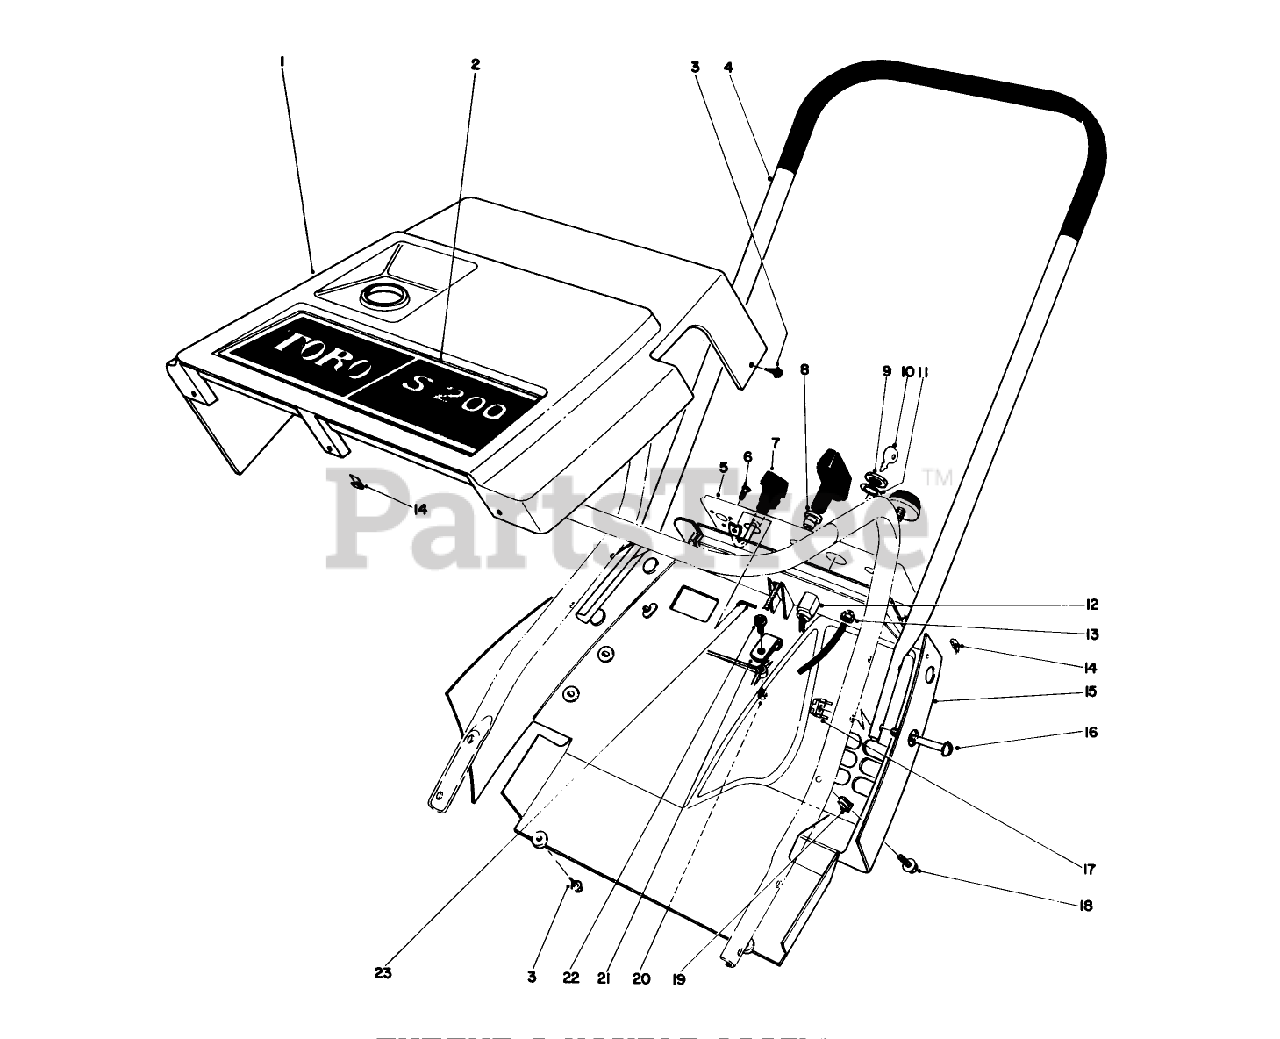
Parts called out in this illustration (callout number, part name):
3	SCREW-HWHTF
6	SCREW-PLASTITE
7	CHOKE CONTROL ASM
8	GUIDE-ROPE, STARTER
9	NUT-HH
11	WASHER-LOCK
13	NUT-KEPS
14	NUT-TYPE J
17	TINNERMAN NUT
18	SCREW-HWHTF
20	NUT-LOCK, NI
22	SCREW-SHWH
23	CONTROL WIRE
